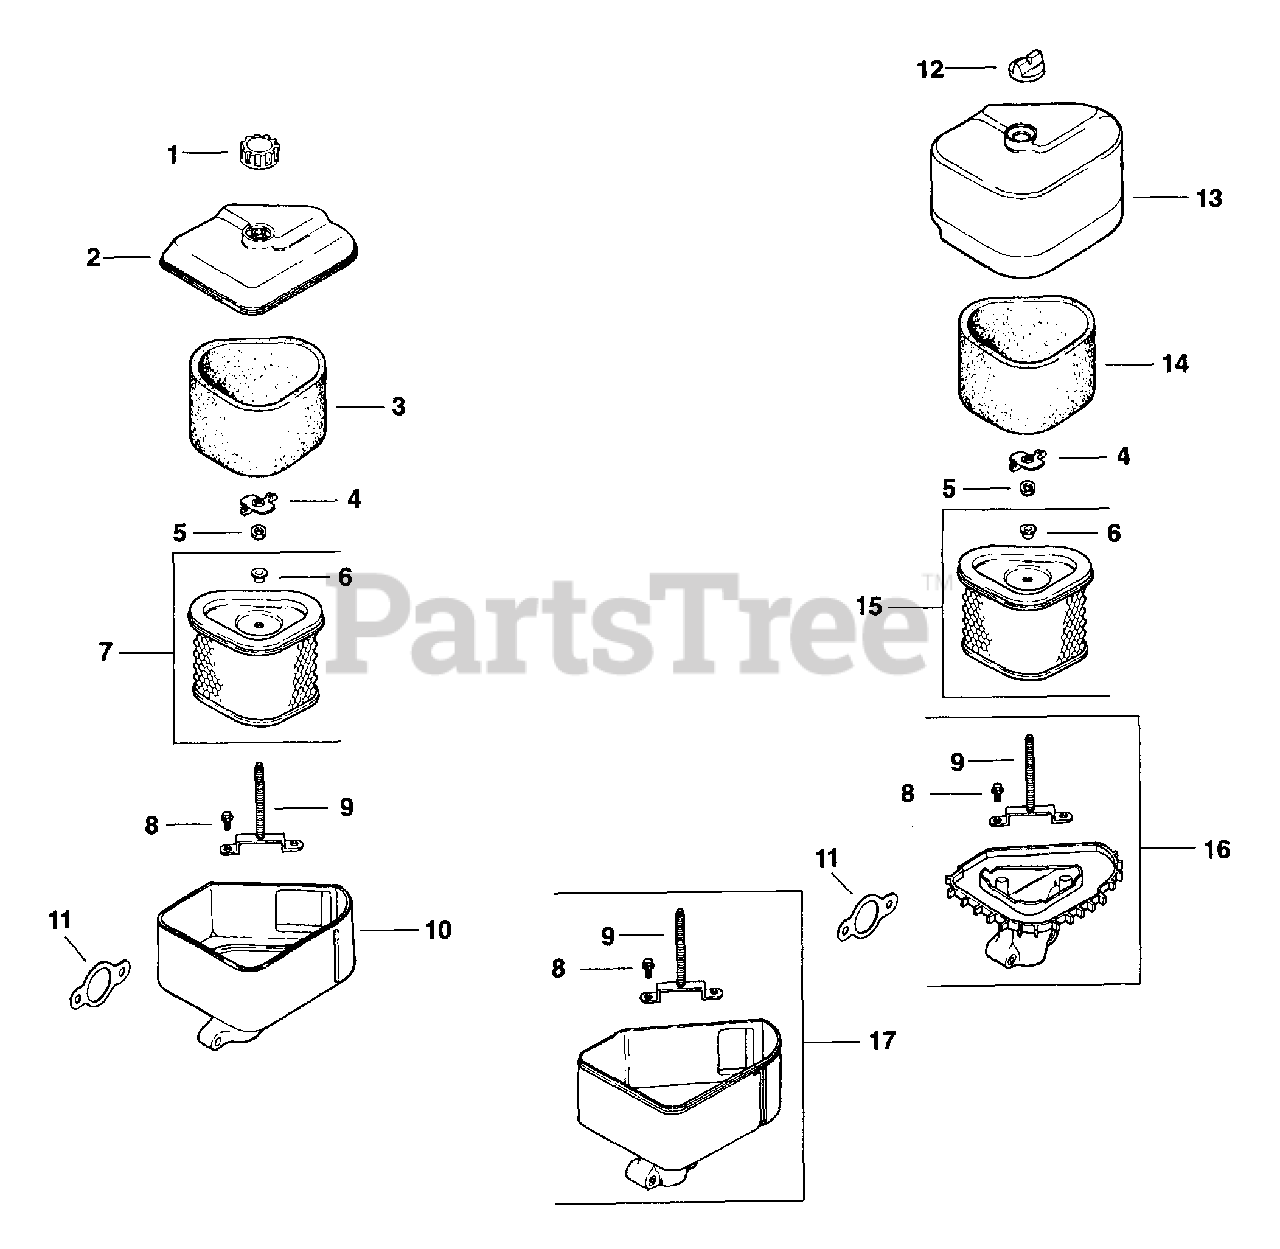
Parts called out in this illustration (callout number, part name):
3	PRE-CLEANER
4	NUT, WING
5	WASHER, FLAT 1/4" (O.D. 1/2")
6	GROMMET - (#DSC)
7	ELEMENT W/SEAL KIT - Also available Retail Packaged 12 883 05-S1 Air Filter Kit
8	SCREW, THD FRM #10 HI-LO
10	BASE - USE 12 094 08
11	GASKET, AIR CLEANER BASE
